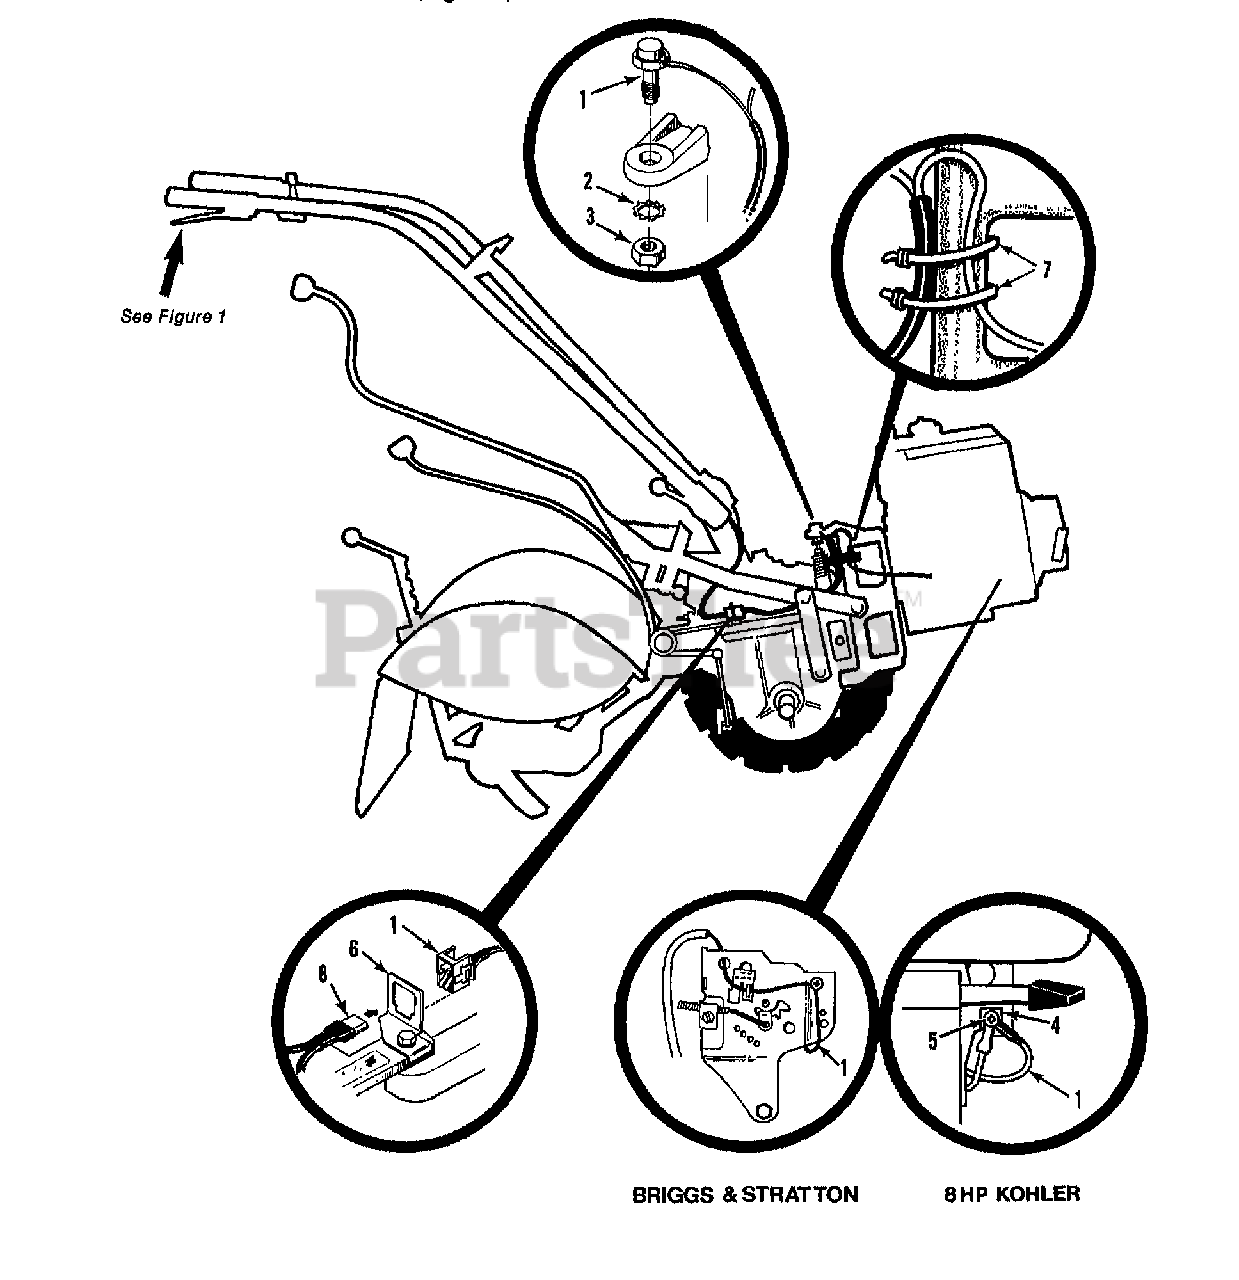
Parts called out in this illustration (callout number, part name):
1	HARNESS-WIRE ENG OPC
2	WASHER-LK .438 EXT TOOTH
3	NUT-HEX/JAM 7/16-20
4	GROMMET-7 T/L & 8 KOH OPC
5	SCR #8-18 SELF TAP
6	CLIP-CONNECTOR
7	TIE-RED
8	HARNESS-WIRE OPC HORSE
